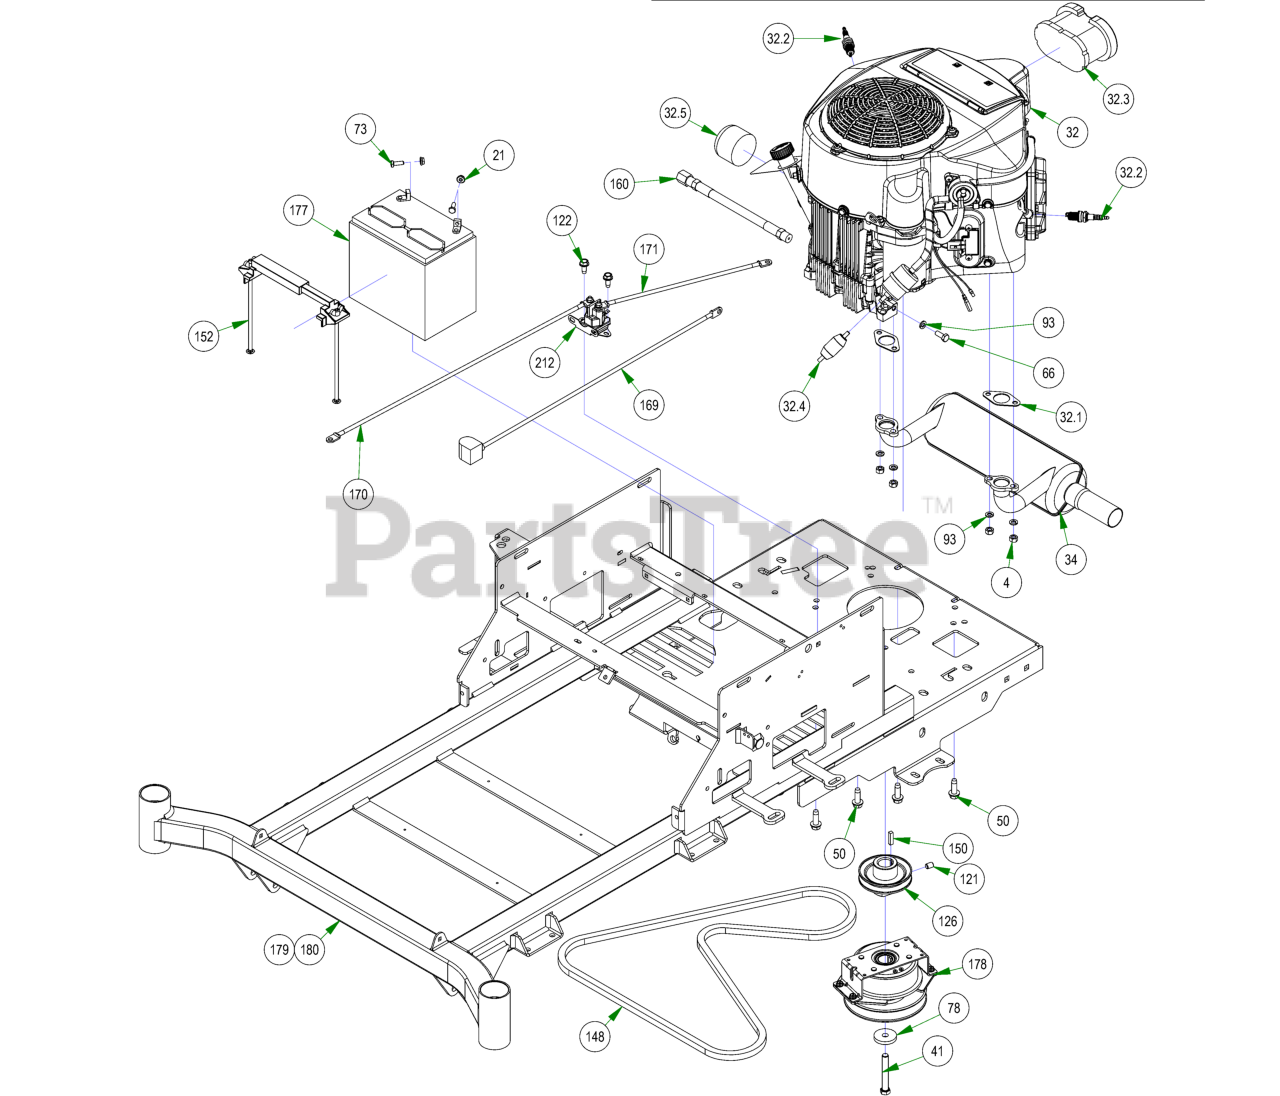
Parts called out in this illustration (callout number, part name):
4	M8-1.25 DIN 934 HEX NUT (CL.8) ZINC
21	1/4-20 HEX SERRATED FLANGE NUT HARD/ZINC
32	726cc Kawasaki Engine-FR651V
32.1	Exhaust Gasket
32.2	Spark Plug - Kawasaki
32.3	Kawasaki Air Filter
32.4	Universal Inline Fuel Filter
32.5	Oil Filter
34	Kawasaki Muffler 1251
41	7/16-20x3” Hex Bolt GR 8 W/ Patch
50	3/8-16 X 1-1/8HEX WASHER UNSLOT SERRATED (TRI-LOB) TRS
66	M8-1.25 X 20MM DIN 933 HEX TAP BOLT (CL 8.8) ZINC
73	1/4-20 X 3/4 HEX CAP SCREW (GR.5) ZINC
78	CLUTCH WASHER
93	5/16 SPLIT LOCKWASHER ZINC
121	3/8-16 X 1/2 SOCKET SET SCREW (CUP PT) PLAIN
122	5/16-18 X 3/4HEX WASHER SLOT (F) TCS ZINC
126	3-3/4" Motor Pulley
150	1/4 X 1 SQ MACHINERY KEY 1018 STL PLN
152	Hold Down Assembly
160	Oil drain Hose
169	24 inch Black Cable – MZ/ZT
170	24" Red Battery Cable
171	12 in red battery cable
177	SP-35 Battery
179	2022 MZ/ZT 54"-60" Frame
180	2022 MZ/ZT 42"-48" Frame
